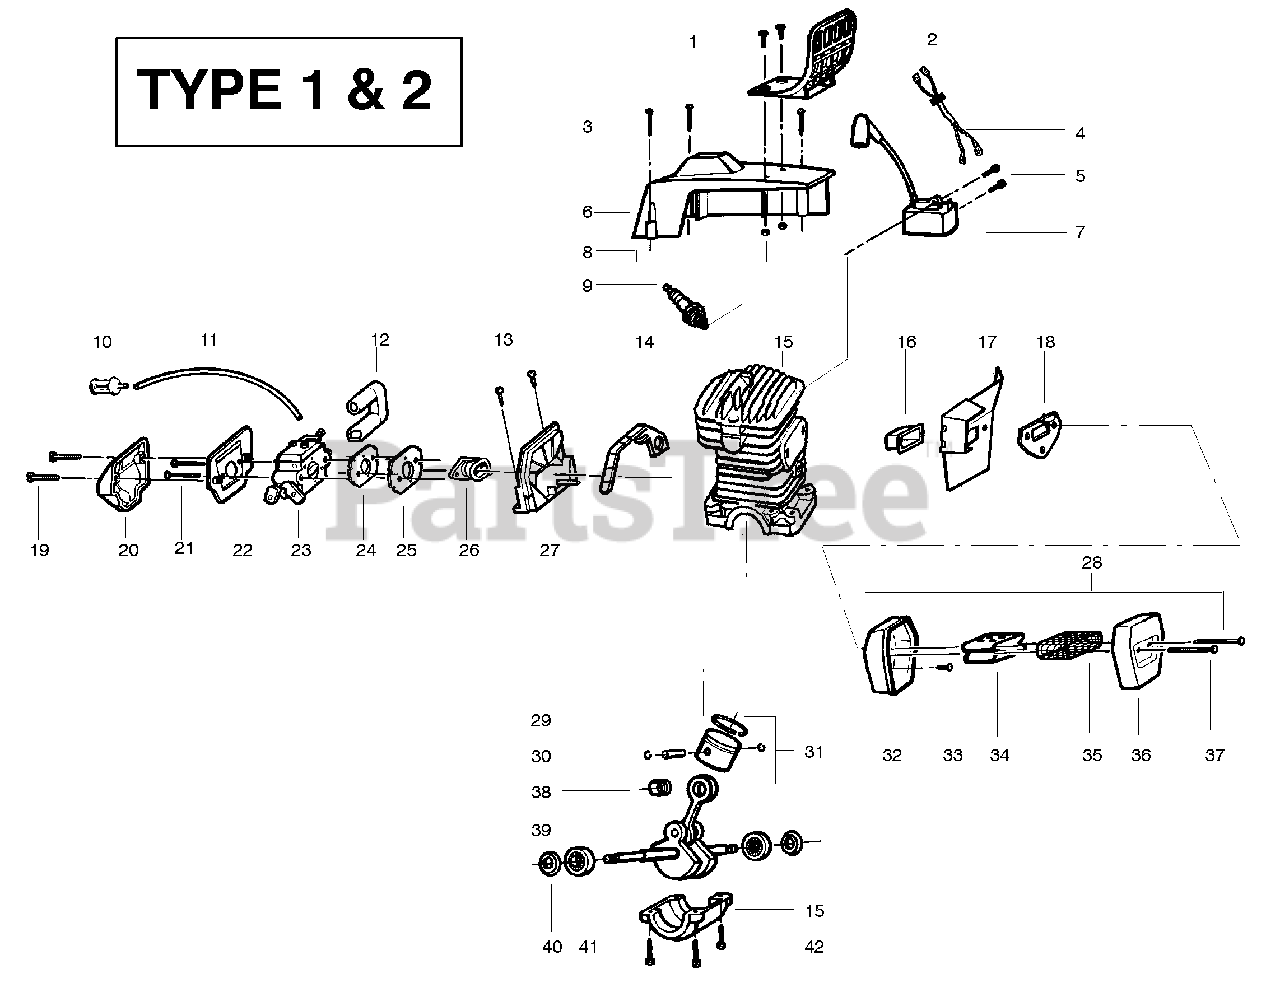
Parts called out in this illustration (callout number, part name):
1	Screw (Type 1 only)
2	Handguard (Type 1 only)
4	Switch Wire Ass'y.
6	Cylinder Shield Kit
7	Ignition Module
8	Nut (Type 1 only)
9	Spark Plug (RCJ-7Y)
10	Fuel Pick-up Assy.
11	Kit - Line Carb / Purge
12	Carb. Grommet
14	Super Clean Seal
15	C'case&Cylinder Assy
16	Heat Insulator
17	Muffler Plate
18	Muffler Gasket
20	Air Filter (Top)
22	Air Filter (Bottom)
23	Carburetor (WT-529)
24	Carburetor Gasket
25	Carburetor Plate
26	Intake Boot
27	Carb. Adaptor
28	Muffler Kit
30	Piston Pin Retainer
31	Piston Kit
36	Muffler Cover
38	Piston Pin Bearing
39	C'shaft & Rod Ass'y.
40	C'shaft Seal
41	C'shaft Bearing
